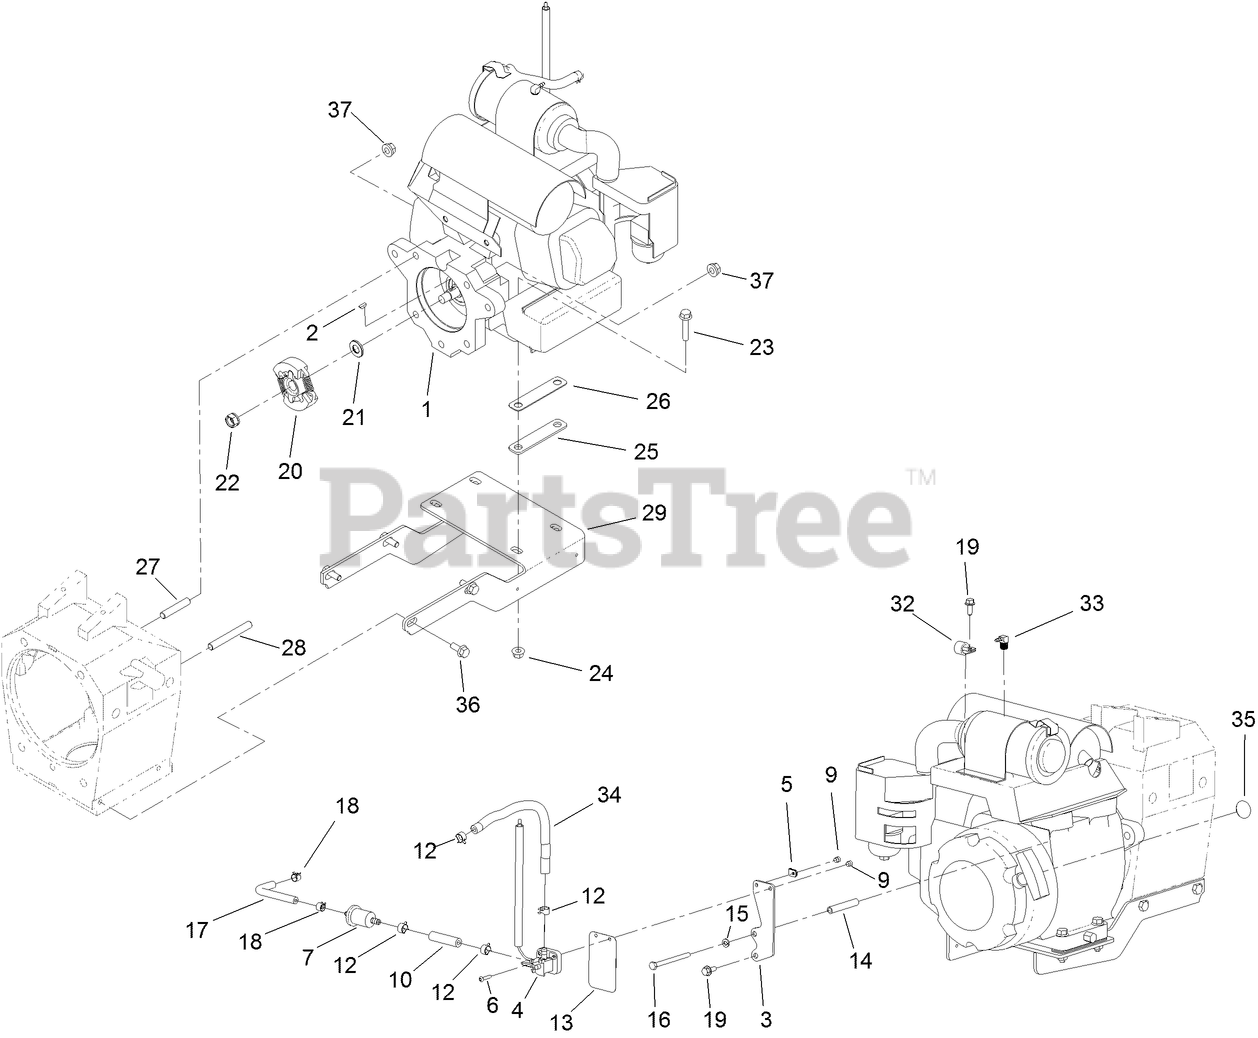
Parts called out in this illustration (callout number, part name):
1	ENGINE-HONDA, GX120
2	KEY-WOODRUFF
3	PLATE-SWITCH, STOP
4	FUEL SHUT OFF VALVE ASM
5	CLAMP-WIRE
6	SCREW-HSBH
7	FILTER-FUEL
9	NUT-LOCK
10	HOSE-FUEL
12	CLAMP-HOSE
13	HANG TAG-RUN, STOP
14	TUBE-SWITCH, STOP
15	WASHER-LOCK, SPRING
16	SCREW-HH
17	HOSE-FUEL
18	CLAMP-HOSE
19	SCREW-HHF
20	CLUTCH-FRICTION
21	SPACER-CLUTCH
22	NUT-HEX FLANGE
23	SCREW-HHF
24	NUT-HF
25	SHIM-ENGINE (11GA)
26	SHIM-ENGINE (16GA)
29	SUPPORT-ENGINE
32	CLAMP-R
33	ELBOW-90
34	HOSE-FUEL
35	PLUG-RUBBER
36	SCREW-HHF
